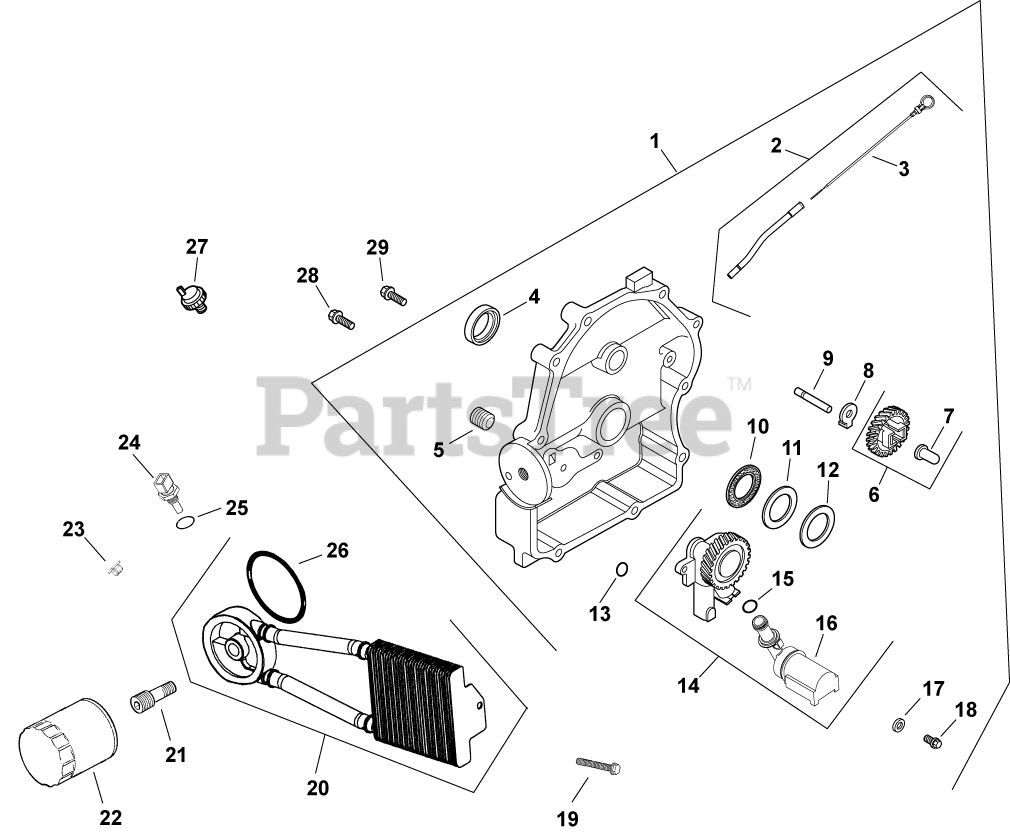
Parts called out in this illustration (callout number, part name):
1	KIT, CLOSURE PLATE USE 24 009 230-S
2	KIT, DIPSTICK/DIPSTICK TUBES
4	SEAL, OIL (KM)-USE 25 032 06-S
5	PLUG, CTSK PIPE 1/8"
6	KIT, GOVERNOR GEAR W/PIN
7	PIN, GOVERNOR REGULATING
8	TAB, LOCKING
9	SHAFT, GOVERNOR GEAR
10	BEARING, THRUST
11	WASHER, THRUST (1MM)
12	SHIM, THRUST (GREEN .875MM) - DISCONTINUED
14	PUMP ASSEMBLY, OIL-USE 24 393 53-S
15	O-RING, OIL PICK-UP
16	PICK-UP, OIL
17	SCREW,FLG THD FRM M6X1.0X25-(#25086395S)
18	WASHER, FLAT 6 MM
19	SCREW, TAP M6X1.7X18
20	COOLER, OIL-USE 24 594 37-S
21	NIPPLE, OIL FILTER
22	OIL FILTER
23	NUT, PLASTIC (KM)-USE 25 100 37-S
24	SENSOR, TEMPERATURE
25	O-RING (.5" DIA)
26	O-RING, OIL COOLER
27	SENSOR, OIL PSI
28	SCREW, HEX FLANGE -USE 24 086 17-S
29	SCREW, FLG M8X1.25X45
2442204-S	SHIM, THRUST (BLUE .5MM)
24755134-S	KIT, WIRING HARNESS (EFI)
